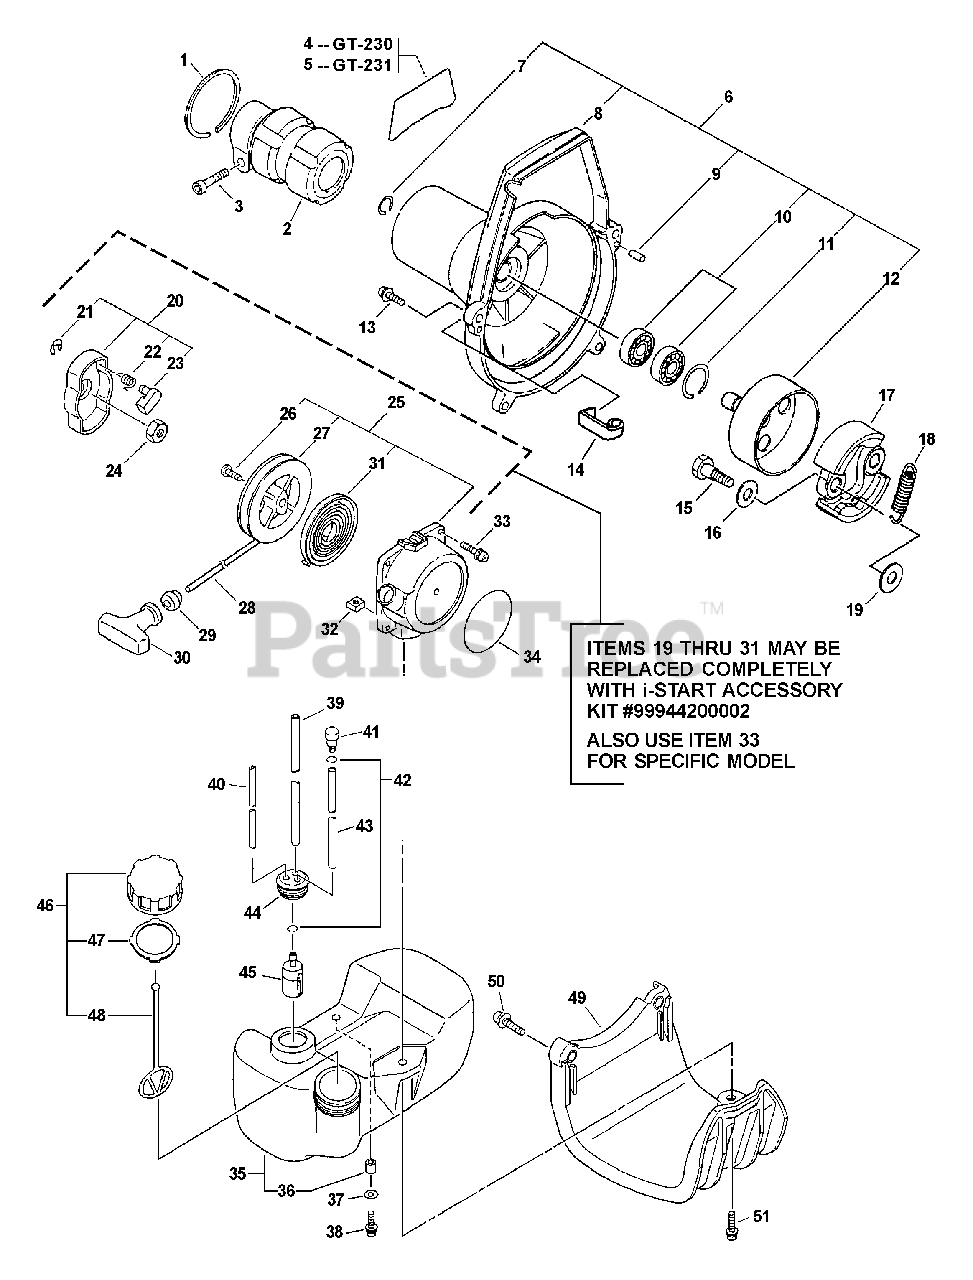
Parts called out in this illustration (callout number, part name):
1	RING, SNAP Ø42
2	HOLDER, MAIN PIPE
3	BOLT 5×28
4	LABEL, MODEL
5	LABEL, MODEL
6	COVER ASSY, FAN - GRAY
7	RING, RETAINING - 12
8	COVER, FAN
9	PIN, LOCATING 4
10	BEARING, BALL 6001
11	RING, SNAP 28
12	DRUM, CLUTCH
13	BOLT 5×18
15	BOLT, CLUTCH 8×7.9×M6
16	WASHER, SPRING 8.5×16×0.5
17	SHOE, CLUTCH
18	SPRING, CLUTCH
19	WASHER 6.2×19×1.0
20	PAWL ASSY, STARTER
21	E-RING 4
22	SPRING, RETURN
23	PAWL, STARTER
24	NUT 8×1.25
25	STARTER ASSY, RECOIL
26	SCREW
27	REEL, ROPE
28	ROPE, STARTER 3.5×850
29	GUIDE, ROPE
30	GRIP, STARTER
31	SPRING, RECOIL
32	NUT M5
33	BOLT 4×12
34	LABEL, ECHO
35	TANK, FUEL
36	SPACER 6.2×7.8×6
37	WASHER 5.5×12×0.8
38	BOLT 5×16
39	PIPE, FUEL 3×6×170
40	PIPE, FUEL 3×6×80 CLEAR
41	VENT ASSY
42	CLIP Ø6.5 MM
43	PIPE 3×6×115 BLACK
44	GROMMET, FUEL
45	FILTER, FUEL
46	CAP ASSY, FUEL
47	GASKET, FUEL CAP
48	CONNECTOR, CAP L= 100 MM
49	GUARD, FUEL TANK
50	BOLT 5×22
51	SCREW 5×20
